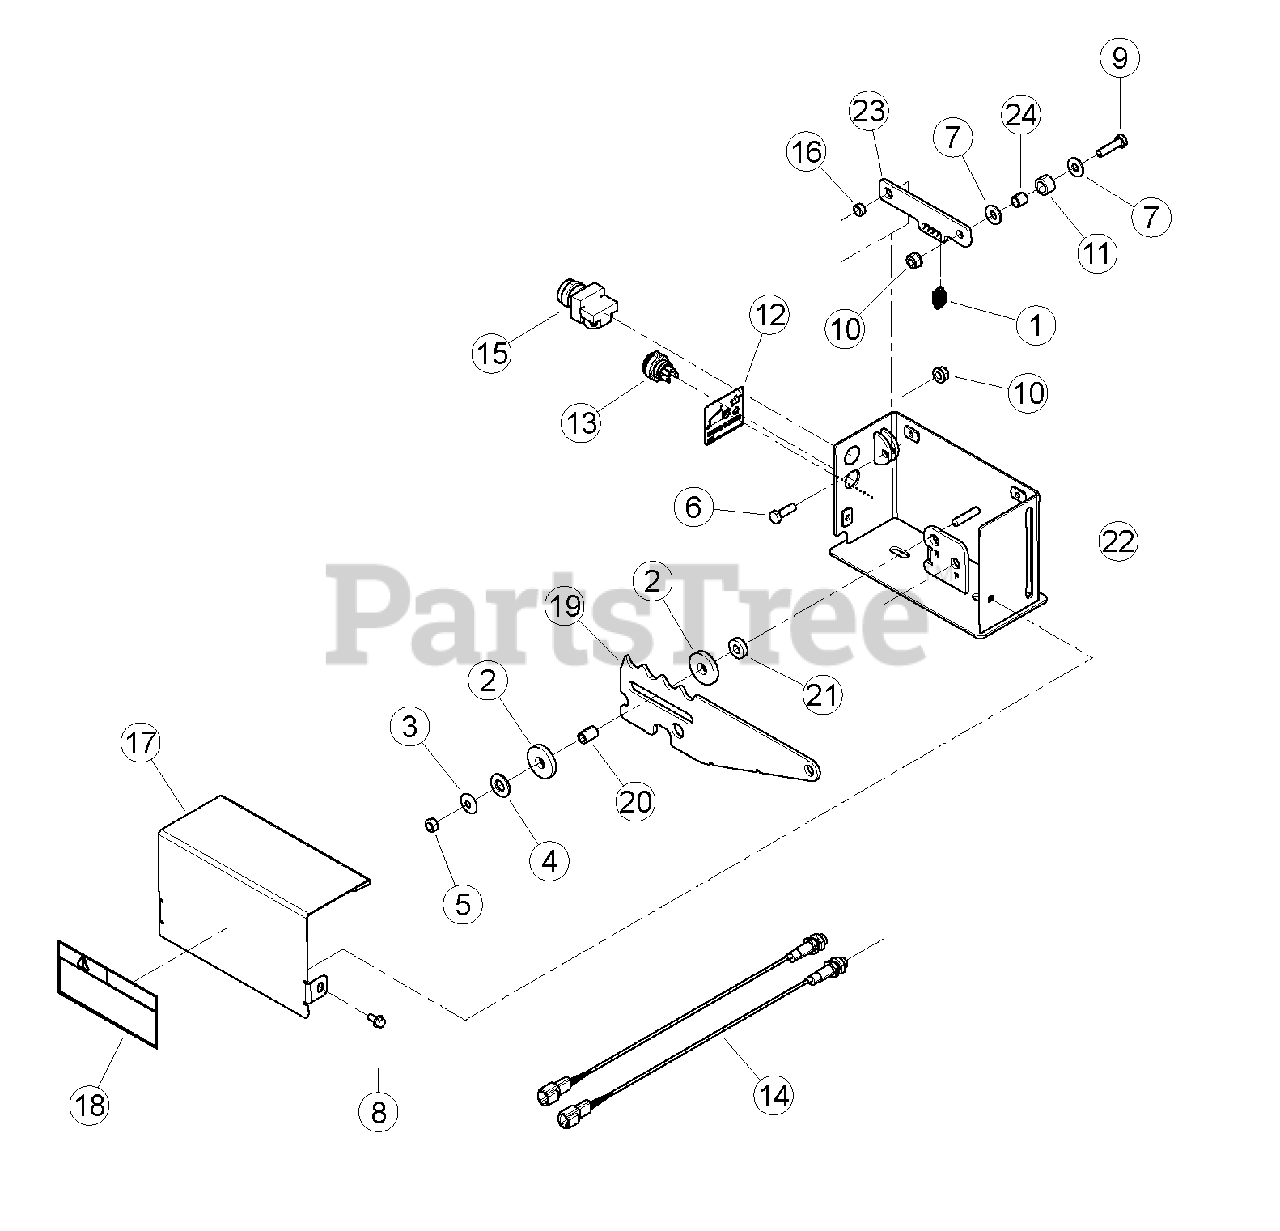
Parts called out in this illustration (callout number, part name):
1	SPRING, CONTROL BAR
2	WASHER, UHMW SPACER .515ID-1.50OD
3	WASHER, SPRING
4	WASHER, 1/2 SAE FLAT ZP
5	NUT, 5/16 CENTERLOCK NC ZP
6	BOLT, 5/16 X 1 HEX GR5 NC ZP
7	WASHER, 5/16 FLAT ZP
8	BOLT, 1/4 X 1/2 SERR FLANGE GR5 ZP
9	BOLT, 5/16 X 1-1/4 HEX GR5 NC ZP
10	NUT, 5/16-18 NYLOCK-FLANGE
11	ROLLER, NYLON .75 OD X .502 ID X .440
12	DECAL, RESET/OVERRIDE
13	LIGHT, LED TRI-COLOR
14	SENSOR, M12 PNP PROXIMITY (REPLACEMENT PART)
15	SWITCH, MOMENTARY IP65 NORMALLY OFF
16	SPACER, IDLER PIVOT
17	ASSEMBLY, CONTROL COVER W/ DECAL
18	DECAL, MULTILINGUAL MANUAL
19	BAR, SWITCH CONTROL
20	SPACER, .50 X .728
21	SPACER, .375 X .25
22	WELDMENT, SWITCH BOX
23	LINK, DETENT
24	SPACER, 1/2 OD X .35 ID X .47
